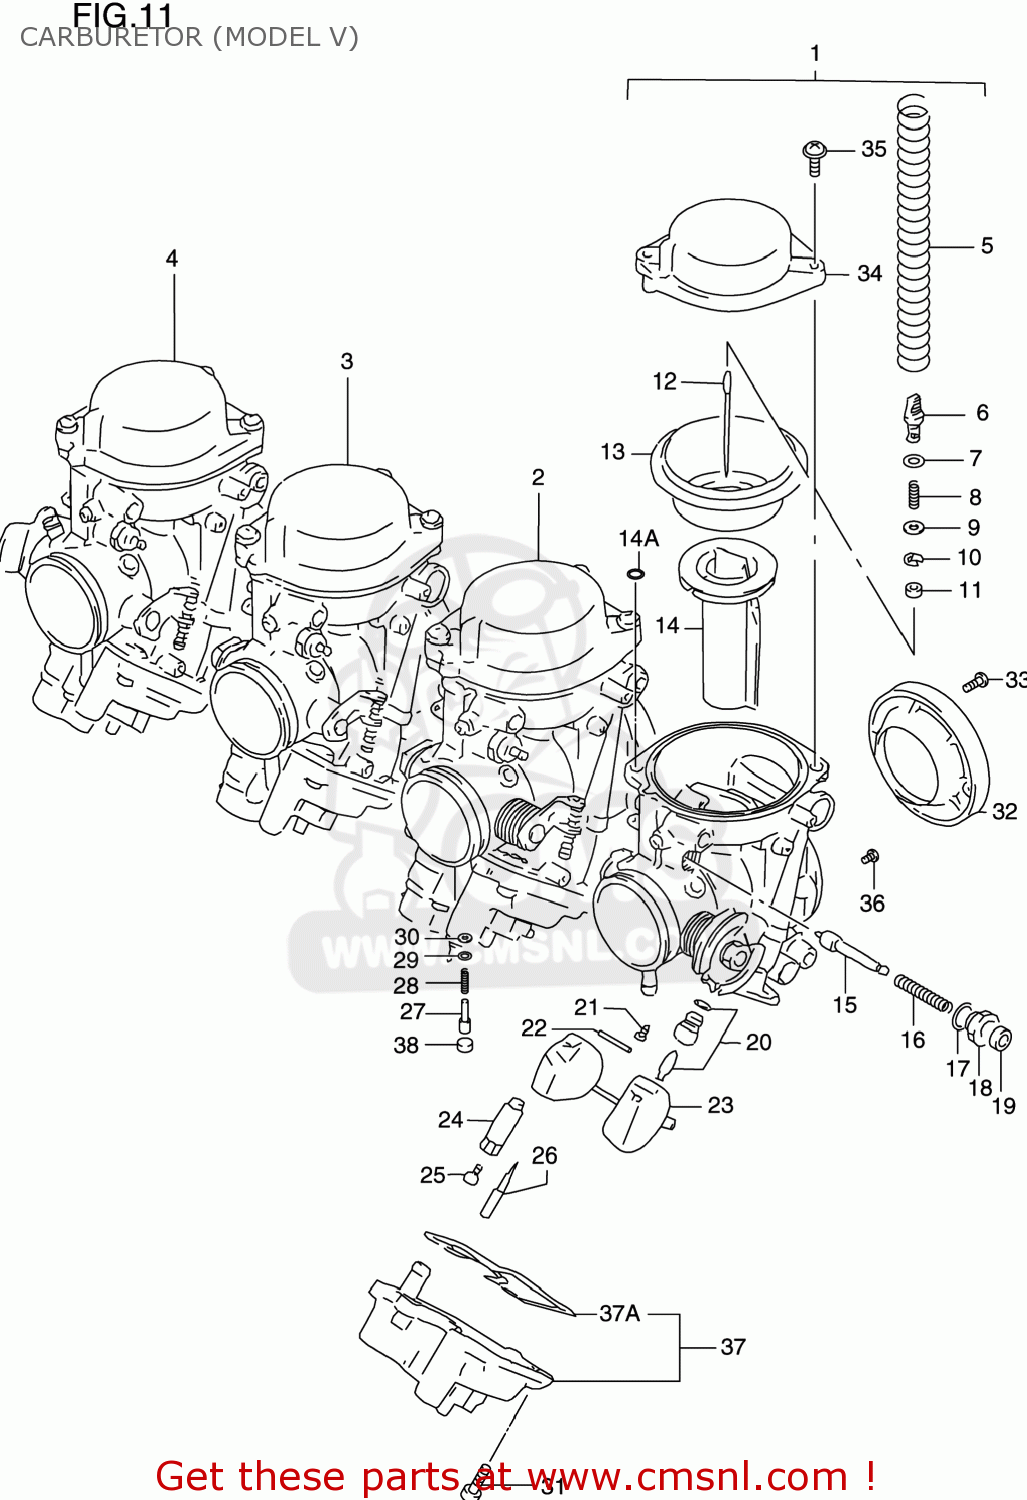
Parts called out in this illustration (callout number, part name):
1	CARBURETOR ASSEMBLY,LEFT
2	CARBURETOR ASSEMBLY,MIDDLE,LEFT
3	CARBURETOR ASSEMBLY,MIDDLE,RIGHT
4	CARBURETOR ASSEMBLY,RIGHT
5	SPRING
6	HOLDER
7	O RING(D:1.9,ID:4.8)
8	SPRING
9	WASHER
10	E RING,MULTIPLE JET NOZZLE
11	RING
12	NEEDLE,JET
13	DIAPHRAGM
14	VALVE,PISTON
14A	O RING
15	PLUNGER
16	SPRING
17	O RING
18	GUIDE SCREW,PLUNGER
19	CAP,STARTER VALVE
20	VALVE ASSEMBLY,NEEDLE
21	SCREW
22	PIN,FLOAT
23	FLOAT ASSY
24	HOLDER,JET
25	JET,MAIN(125)
26	JET,PILOT(12.5)
27	ADJUSTER
28	SPRING,THROTTLE SCREW
29	WASHER
30	O RING,PILOT AIR SCREW
31	SCREW
32	FUNNEL
33	SCREW
34	COVER ASSY,DIAPHRAGM
35	SCREW
36	JET,MAIN(135)
37	BODY ASSY,FLOAT,L
37A	O RING
38	PLUG
